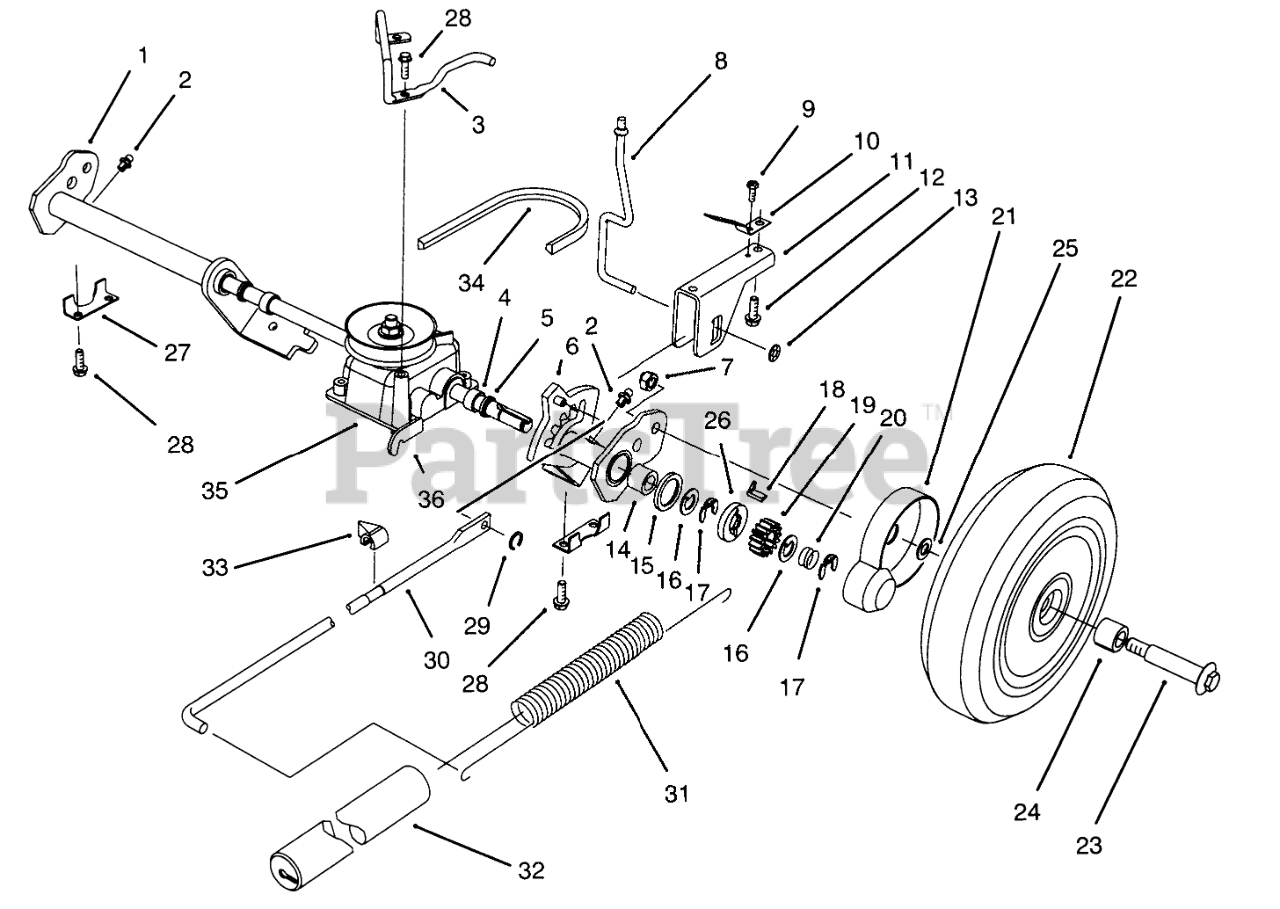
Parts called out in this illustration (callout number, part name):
1	Rear Pivot Assembly R.H.(Incl Ref. #2,4,5,14)
2	FITTING-GREASE
3	Retainer Belt
4	BUSHING
5	SEAL-OIL
6	Rear Pivot Assembly L.H. (Incl Ref.#2,4,5,14)
7	NUT-HEX
8	TRIGGER ROD
9	SCREW 8 - 32 X 250
10	SPRING - TRIGGER RET
11	SADDLE - HOC
12	SCREW
13	PUSHNUT
14	BEARING-ROLLER
15	RING-FRICTION
16	WASHER-THRUST, KEYED
17	RING-CLIP, LOCKING
18	KEY-ROCKING, LH
19	GEAR-PINION
20	SPRING-COMPRESSION
21	COVER-WHEEL
22	Wheel, Tire & Gear Assy(Incl Ref. #24)
23	BOLT-WHEEL
24	BOLT-WHEEL
25	SPACER-COVER, WHEEL
26	WASHER-CLUTCH
27	REAR SECURING PLATE
28	SCREW-HWH
29	GRIP RING
30	LINK ROD
31	SPRING-COUNTERBALANCE
32	COVER-SPRING
33	INDICATOR-HEIGHT OF CUT
34	V-BELT
35	Gearcase Assembly(Incl Ref. #36)
36	Bracket-Traction
